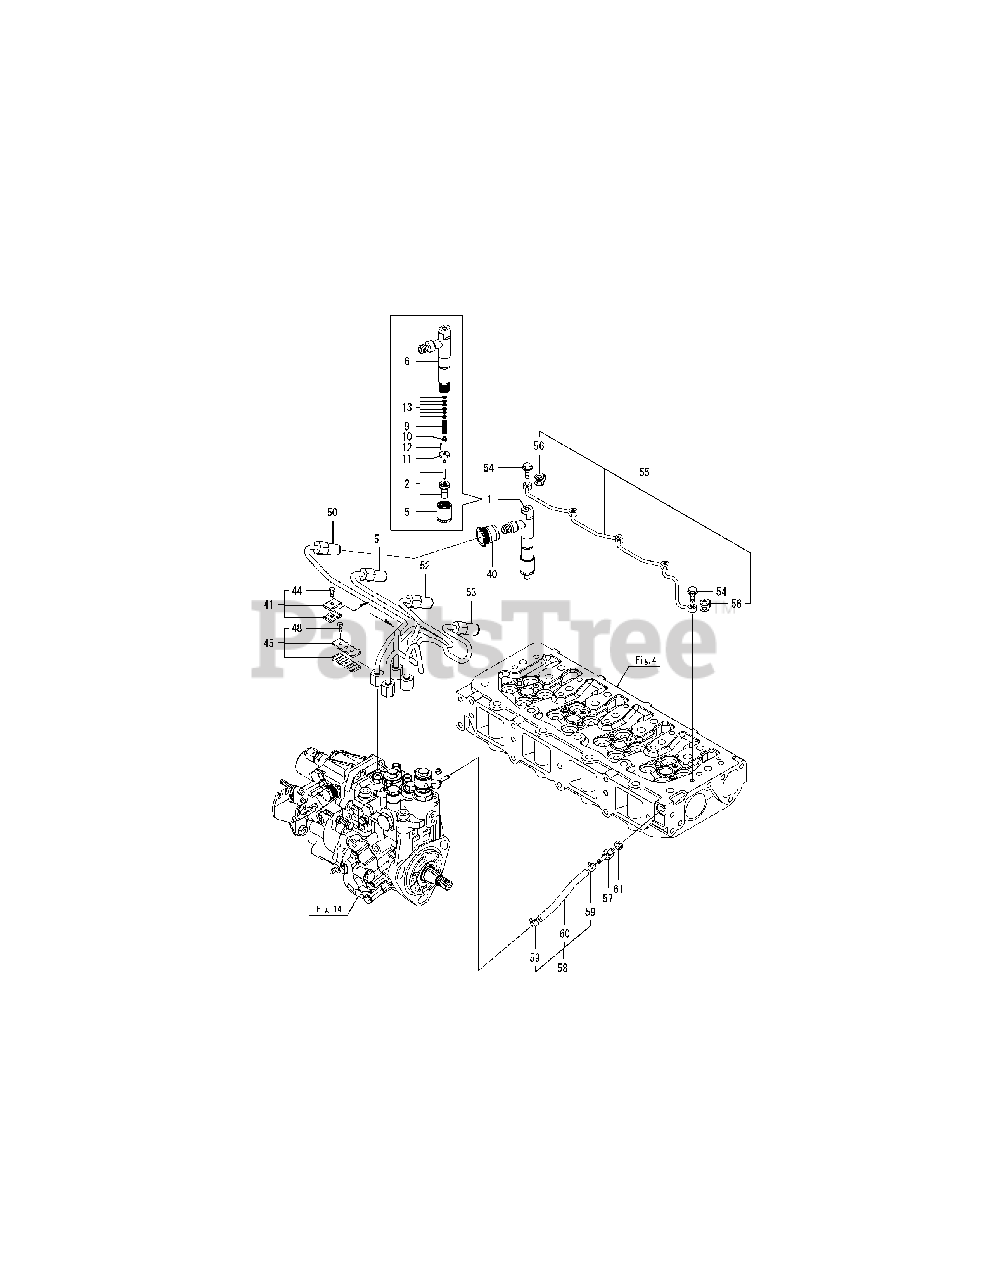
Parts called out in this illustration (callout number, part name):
1	VALVE ASSY,INJECTION
2	VALVE ASSY,INJECTION
6	HOLDER ASSY, NOZZLE
9	SPRING, NOZZLE
13	SHIM SET
44	BOLT M4X14,HEX.SCKT.
45	RETAINER, PIPE
48	BOLT M4X14,HEX.SCKT.
50	PIPE ASSY, INJECTION
51	PIPE ASSY, INJECTION
52	PIPE ASSY, INJECTION
53	PIPE ASSY, INJECTION
54	BOLT, JOINT M6
55	PIPE ASSY, RETURN
58	PIPE ASSY, RETURN
60	PIPE, FUEL RETURN
61	SEAL WASHER 8S
